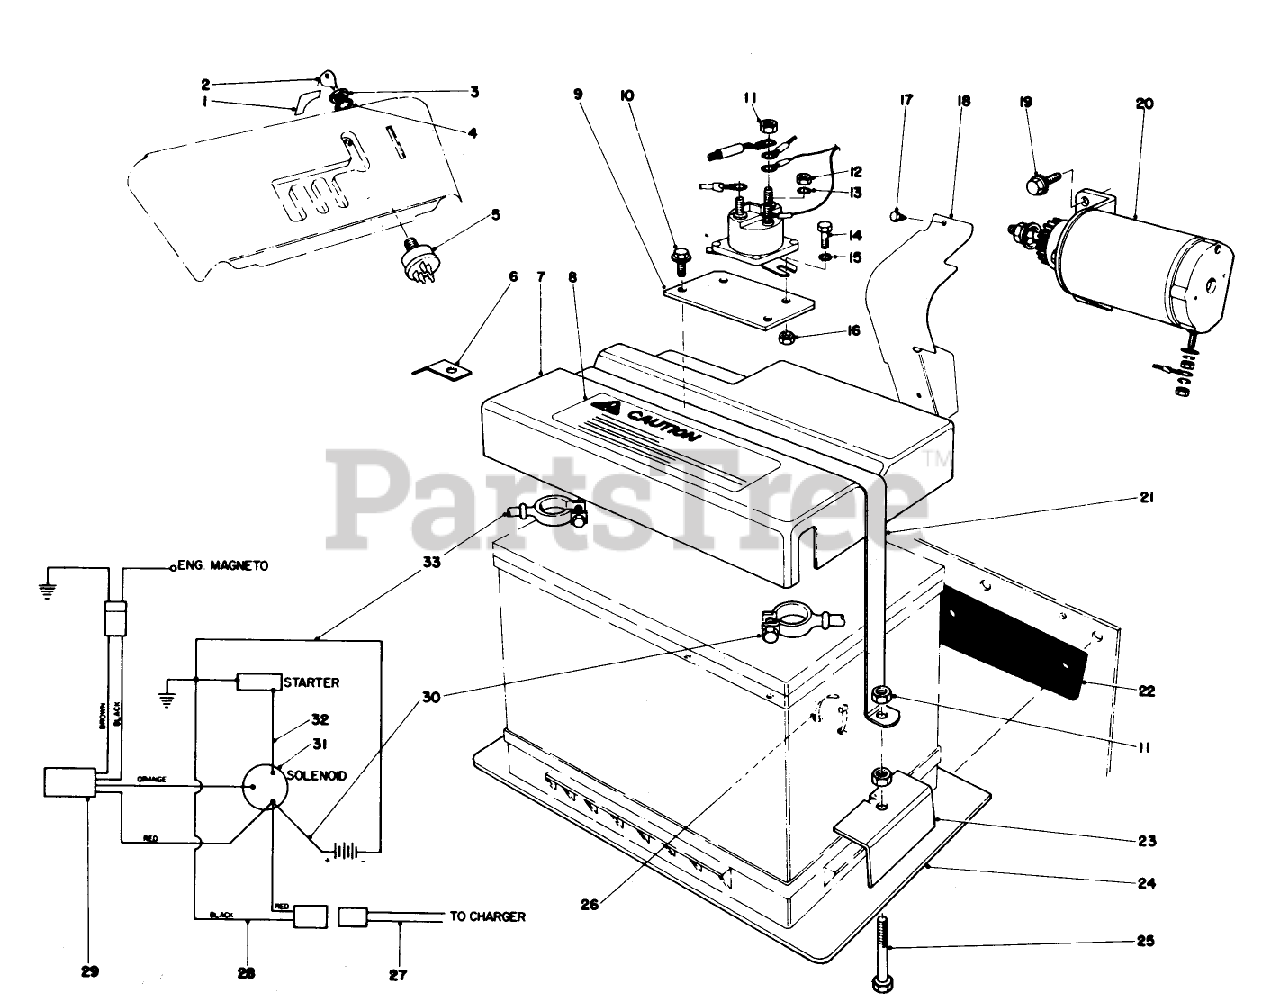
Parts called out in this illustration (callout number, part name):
3	NUT-HH
4	WASHER-LOCK
5	SWITCH-STARTER
10	Screw
11	NUT-HEX
12	NUT-HEX
13	WASHER-LOCK, INT
14	SCREW-HH
15	WASHER-LOCK/EXT
16	NUT-LOCK, NI
18	BRIGGS 280265
19	5/16-18X3/4 HX HD SEM
20	Starter Motor Pinion Assy.
25	SCREW-HH
26	TIE-CABLE
27	MALE WIRE ASM
30	BATT-SOLENOID CABLE
31	SOLENOID
